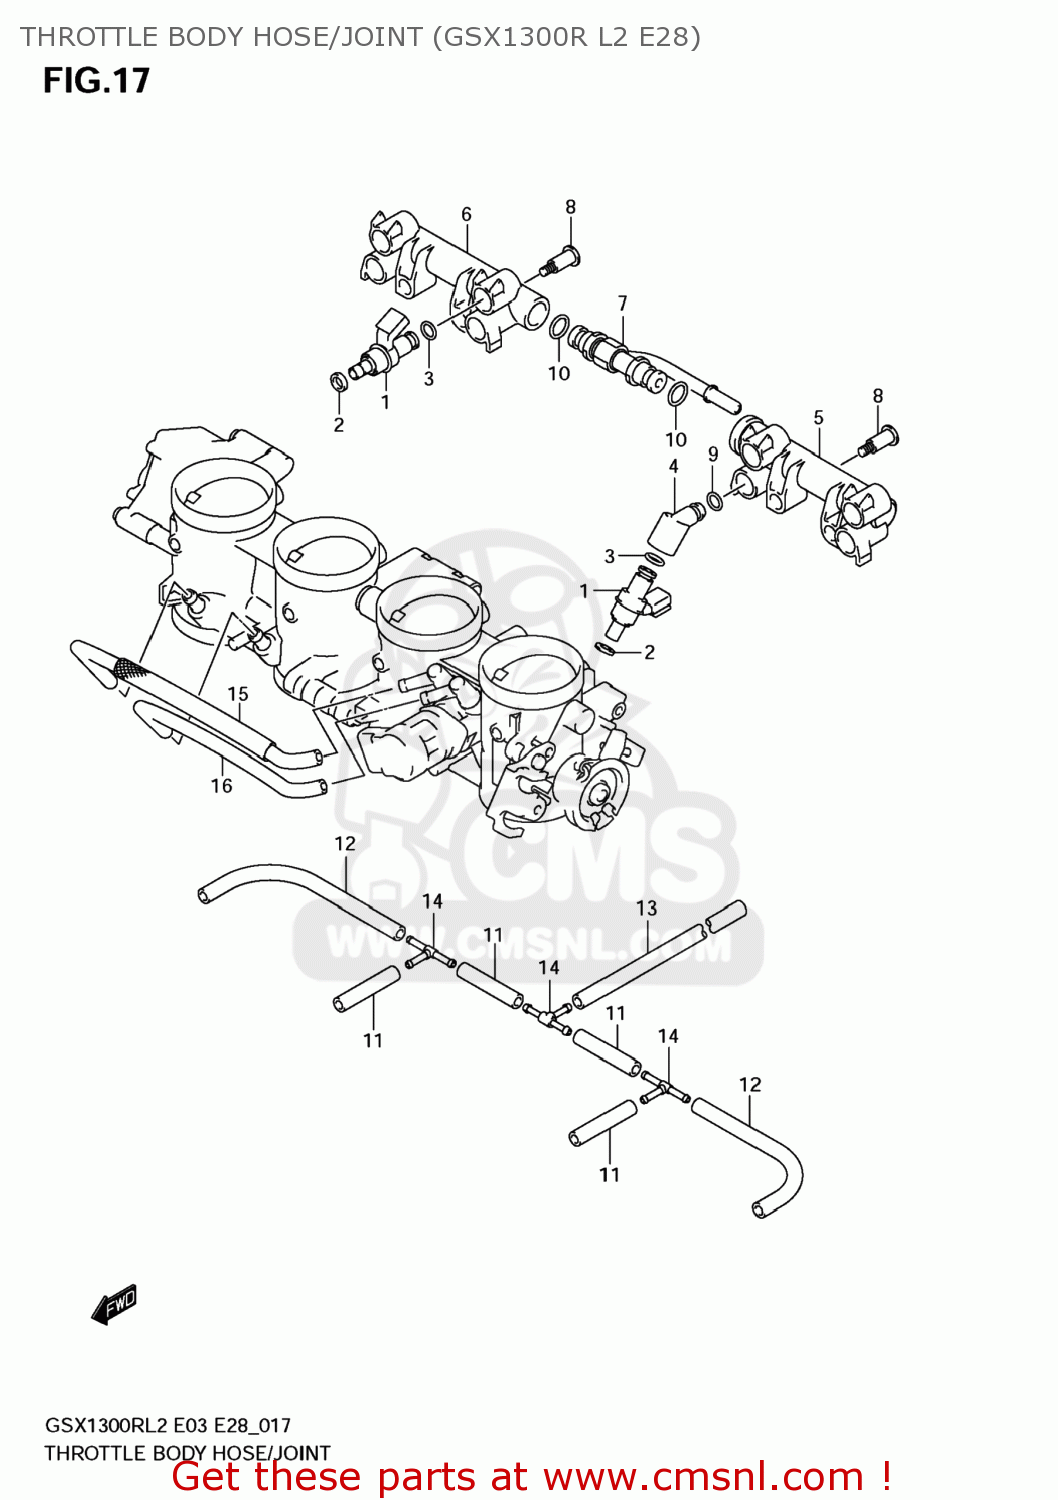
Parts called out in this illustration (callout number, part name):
1	INJECTOR ASSY
2	RING,SEAL
3	O RING
4	PIPE,FUEL
5	PIPE,FUEL
6	PIPE,FUEL
7	JOINT
8	SCREW
9	O RING
10	O RING
11	HOSE,RUBBER(L:35)
12	HOSE,RUBBER(L:100)
13	HOSE,RUBBER(3X7X170)
14	JOINT
15	TUBE
16	TUBE
